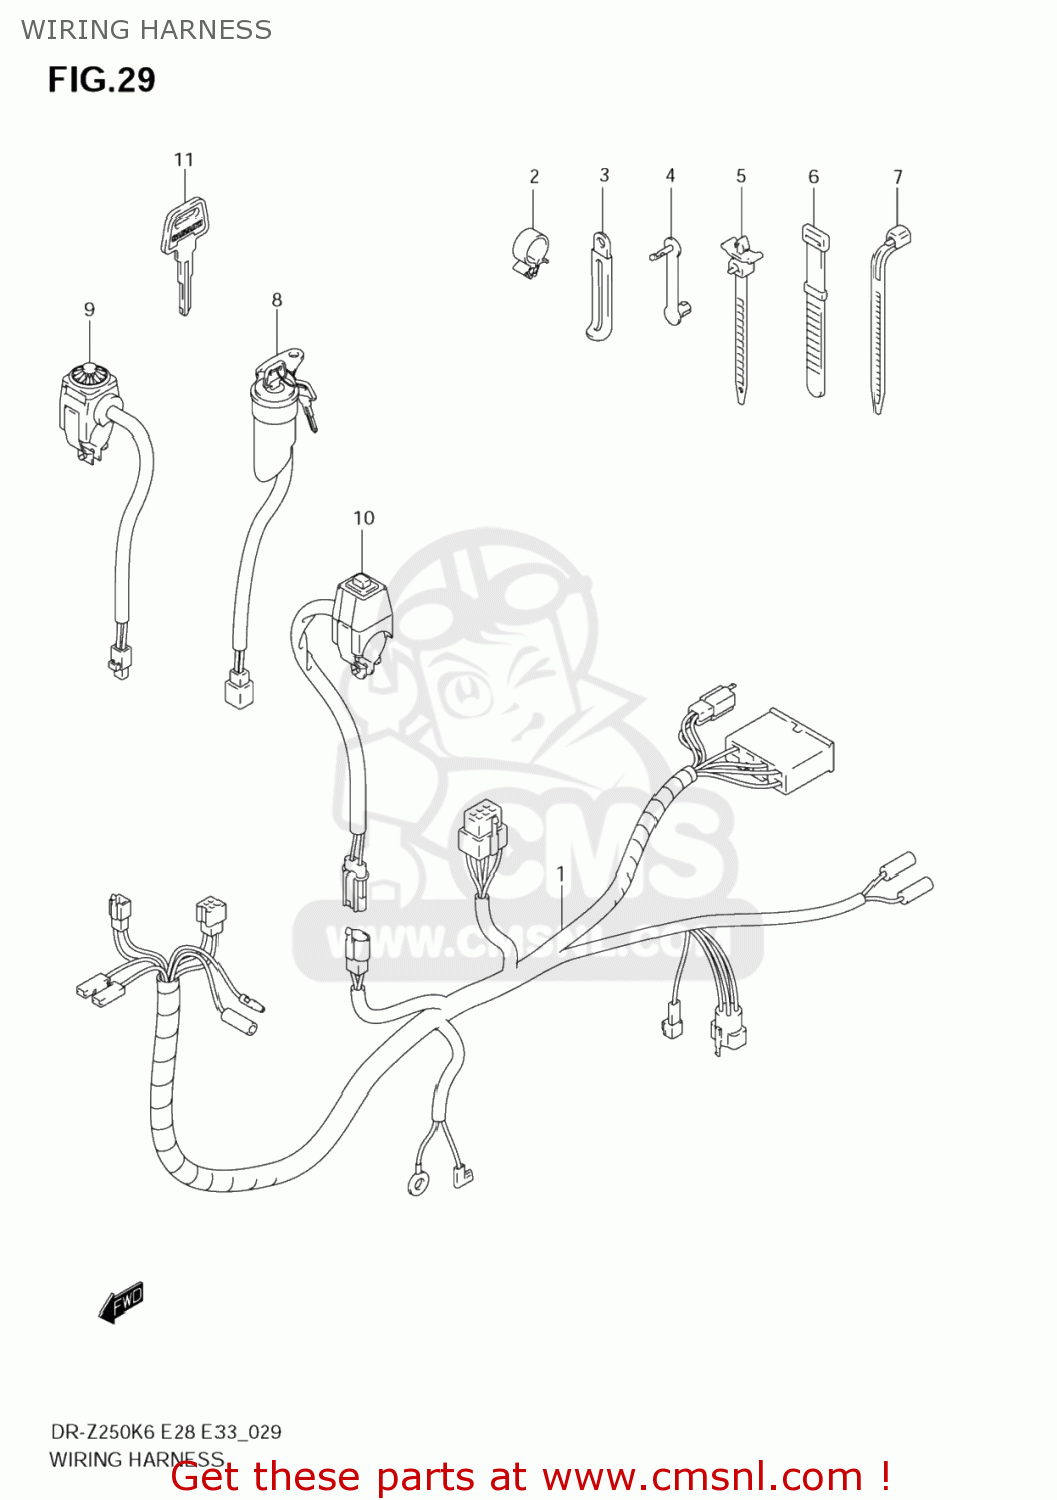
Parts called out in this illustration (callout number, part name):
1	HARNESS,WIRING
2	CLAMP
3	CLAMP(L:100)
4	CLAMP(L:33)
5	CLAMP(L:90)
6	CLAMP(L:120)
7	CLAMP(L:235)
8	SWITCH ASSY,IGNITION
9	SWITCH ASSY,STARTER
10	SWITCH ASSY,ENGINE STOP
11	KEY,BLANK(TYPE:C)
